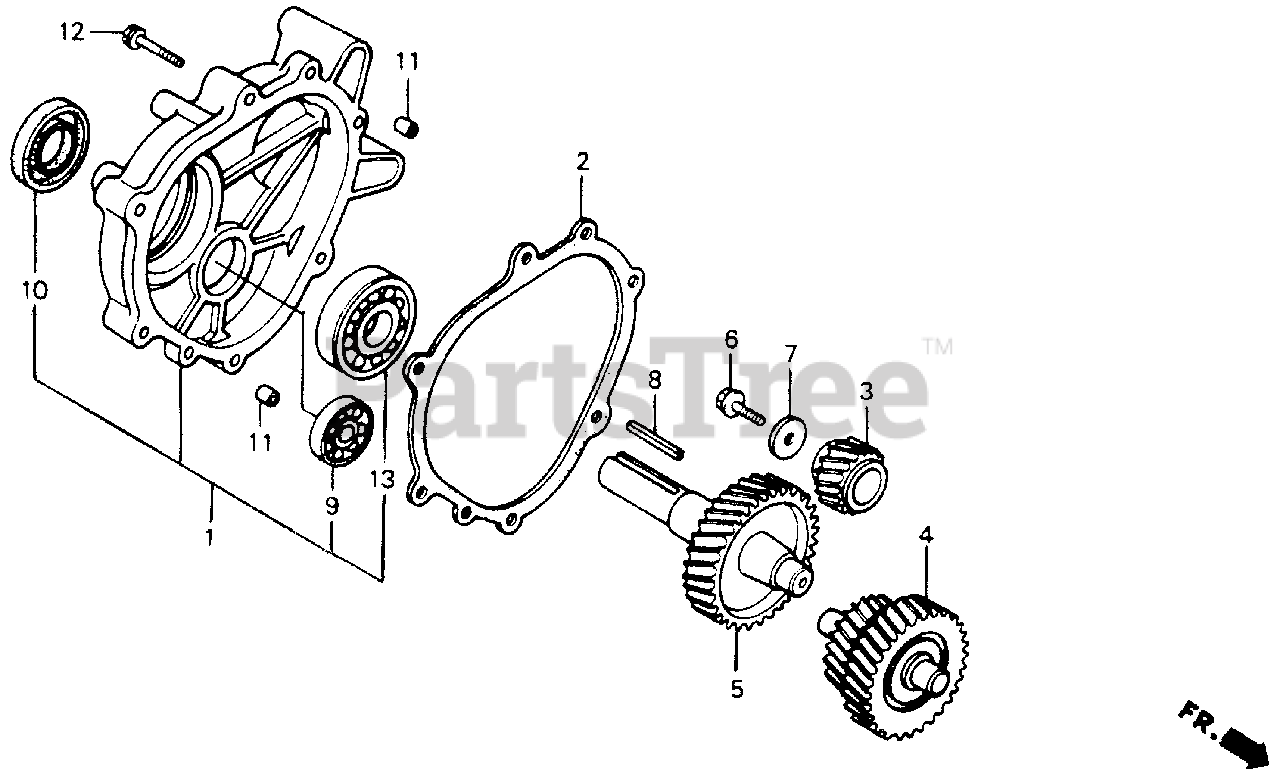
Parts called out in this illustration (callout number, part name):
1	COVER ASSY., GEAR CASE
2	GASKET, CHAIN CASE COVER
3	GEAR, PRIMARY DRIVE
4	COUNTERSHAFT
5	SHAFT, P.T.O. (L-TYPE)
6	BOLT, HEX. (8X25)
7	WASHER (8MM)
8	KEY (7X7X33)
9	BEARING, RADIAL BALL (6202)
10	OIL SEAL (30X46X8)
11	PIN A, DOWEL (8X14)
12	BOLT, FLANGE (8X40)
13	BEARING, RADIAL BALL (6206)
